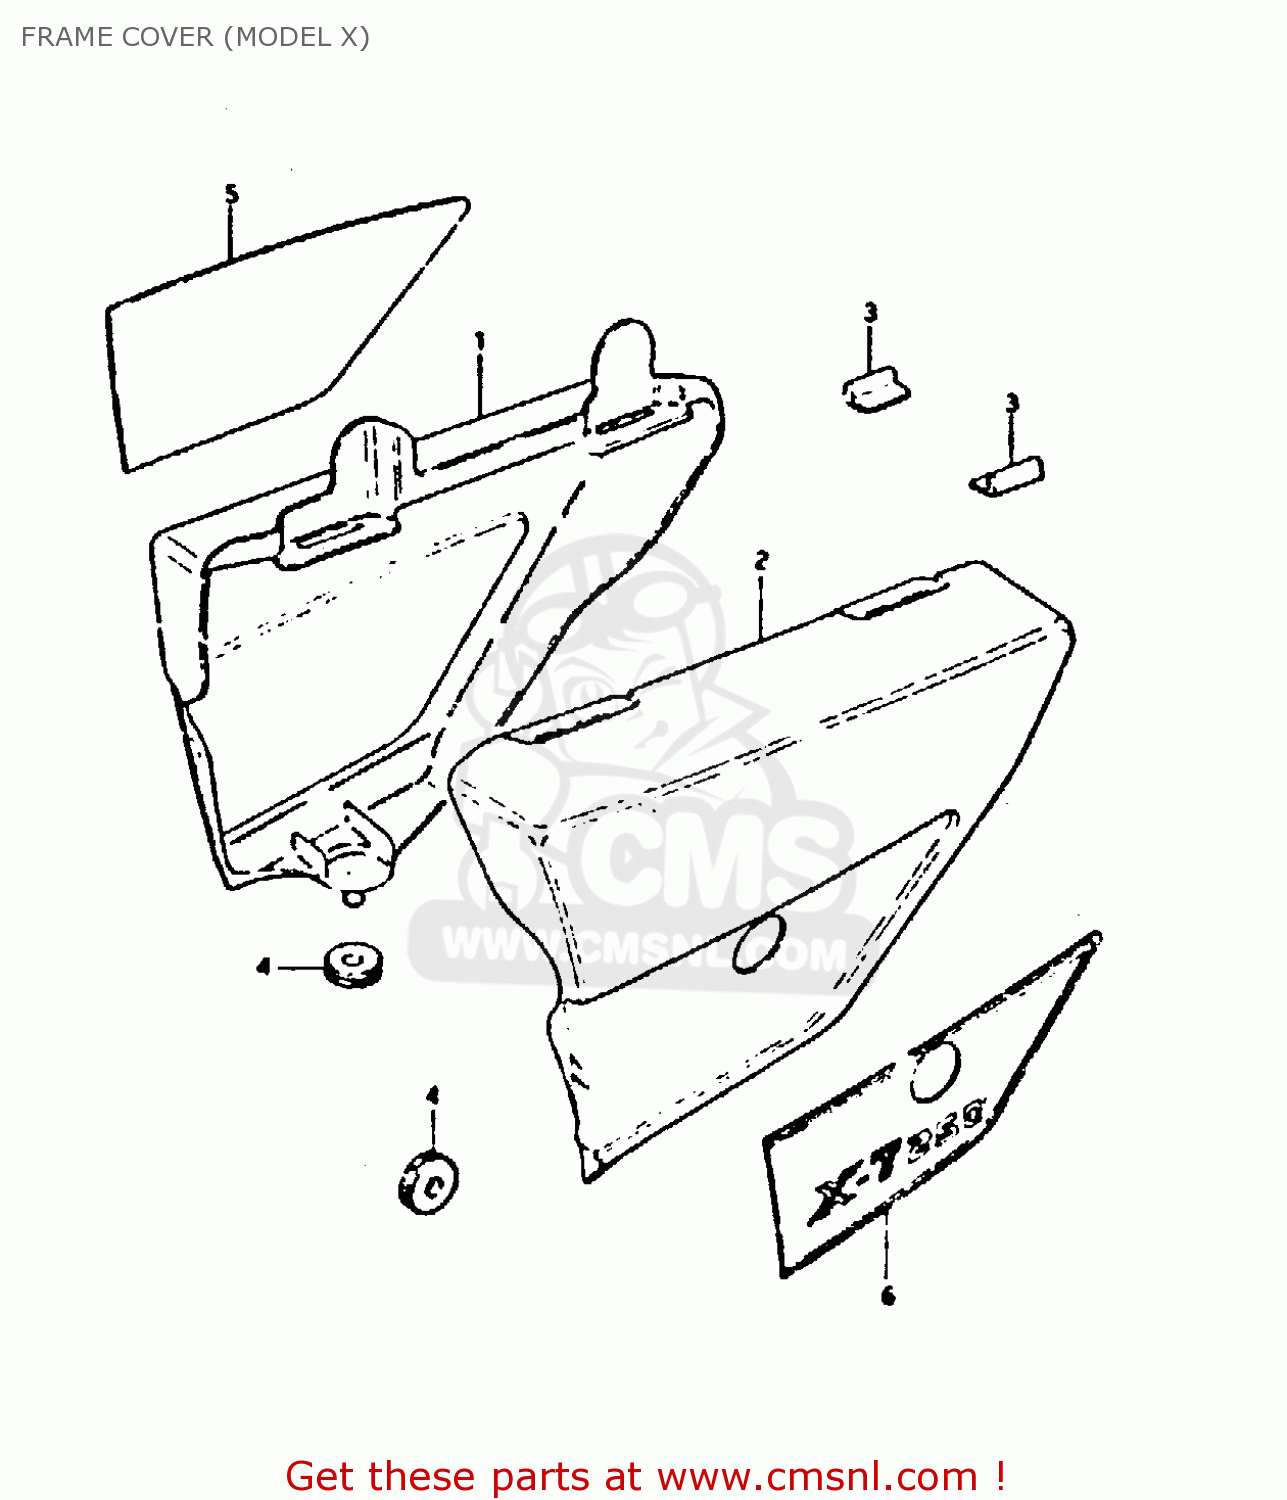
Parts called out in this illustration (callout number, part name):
1	COVER, RH (BLUE)
2	COVER, LH (RED)
3	CUSHION,FRAME COVER
4	CUSHION
5	EMBLEM, RH
6	EMBLEM, LH
